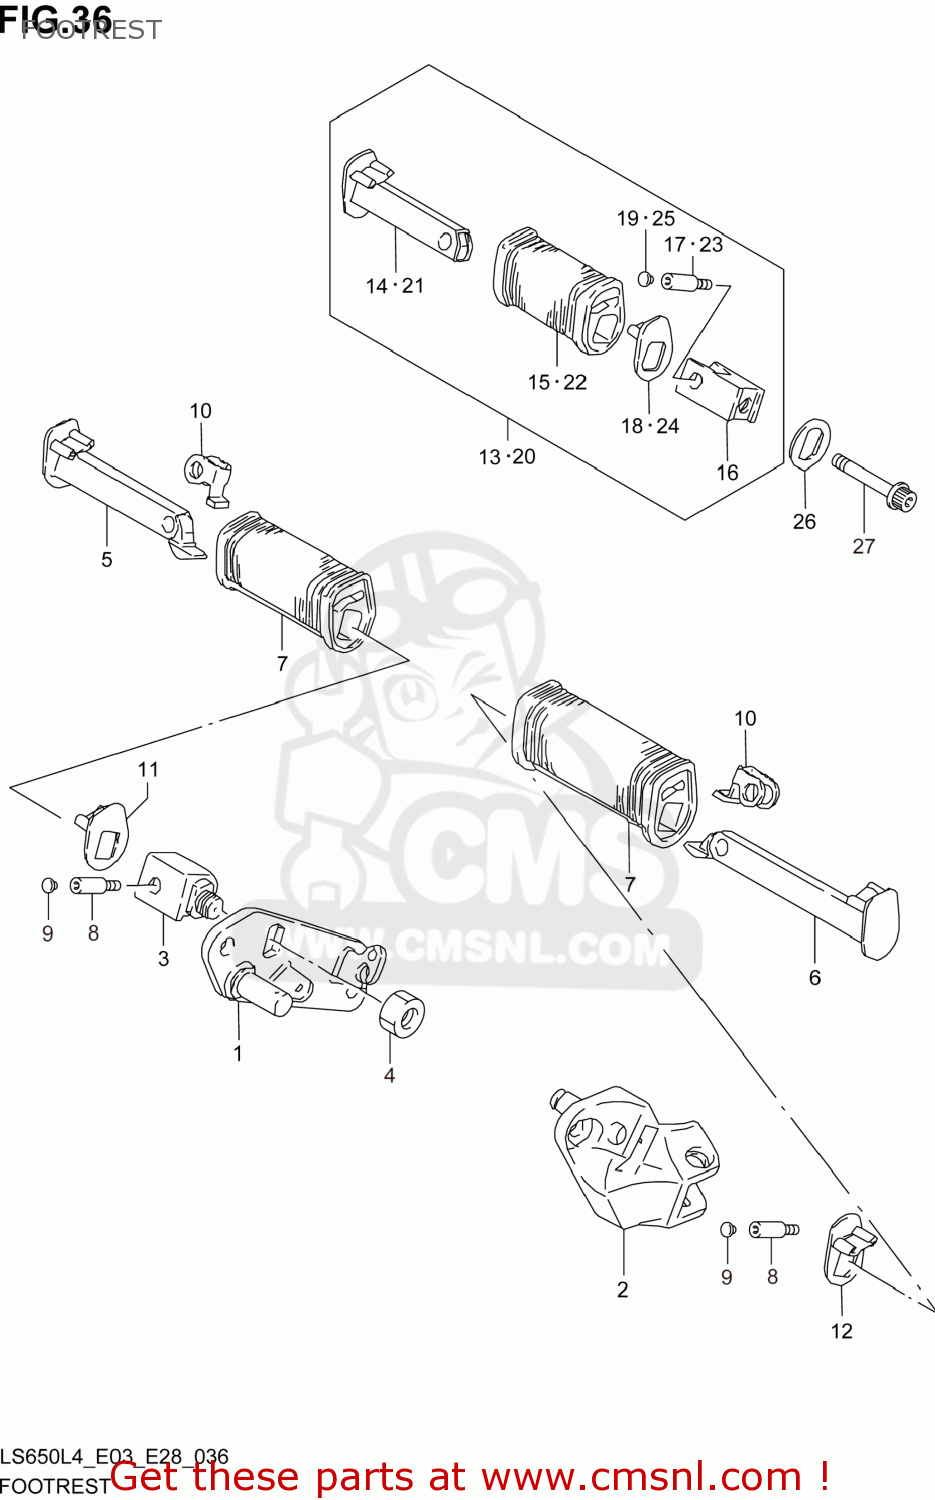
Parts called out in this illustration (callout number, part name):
1	BRACKET,FR FOOTREST,R
2	BRACKET,FR FOOTREST,L
3	HOLDER,FR FOOTREST,R
4	NUT
5	BAR,FR FOOTREST,R
6	BAR,FR FOOTREST,L
7	RUBBER,FR FOOTREST
8	BOLT(6X8)
9	CAP,PILLION FOOTREST BOLT
10	CUSHION,FR FOOTREST
11	WASHER,FR FOOTREST,R
12	WASHER,FR FOOTREST,L
13	FOOTREST ASSY,PILLION,R
14	BAR,PILLION FOOTREST,R
15	RUBBER,PILLION FOOTREST
16	HOLDER,PILLION FOOTREST
17	BOLT(6X8)
18	WASHER,FR FOOTREST,R
19	CAP,PILLION FOOTREST BOLT
20	FOOTREST ASSY,PILLION,L
21	BAR,PILLION FOOTREST,L
22	RUBBER,PILLION FOOTREST
23	BOLT(6X8)
24	WASHER,FR FOOTREST,L
25	CAP,PILLION FOOTREST BOLT
26	WASHER,PILLION FOOTREST HOLDER
27	BOLT(10X45)
